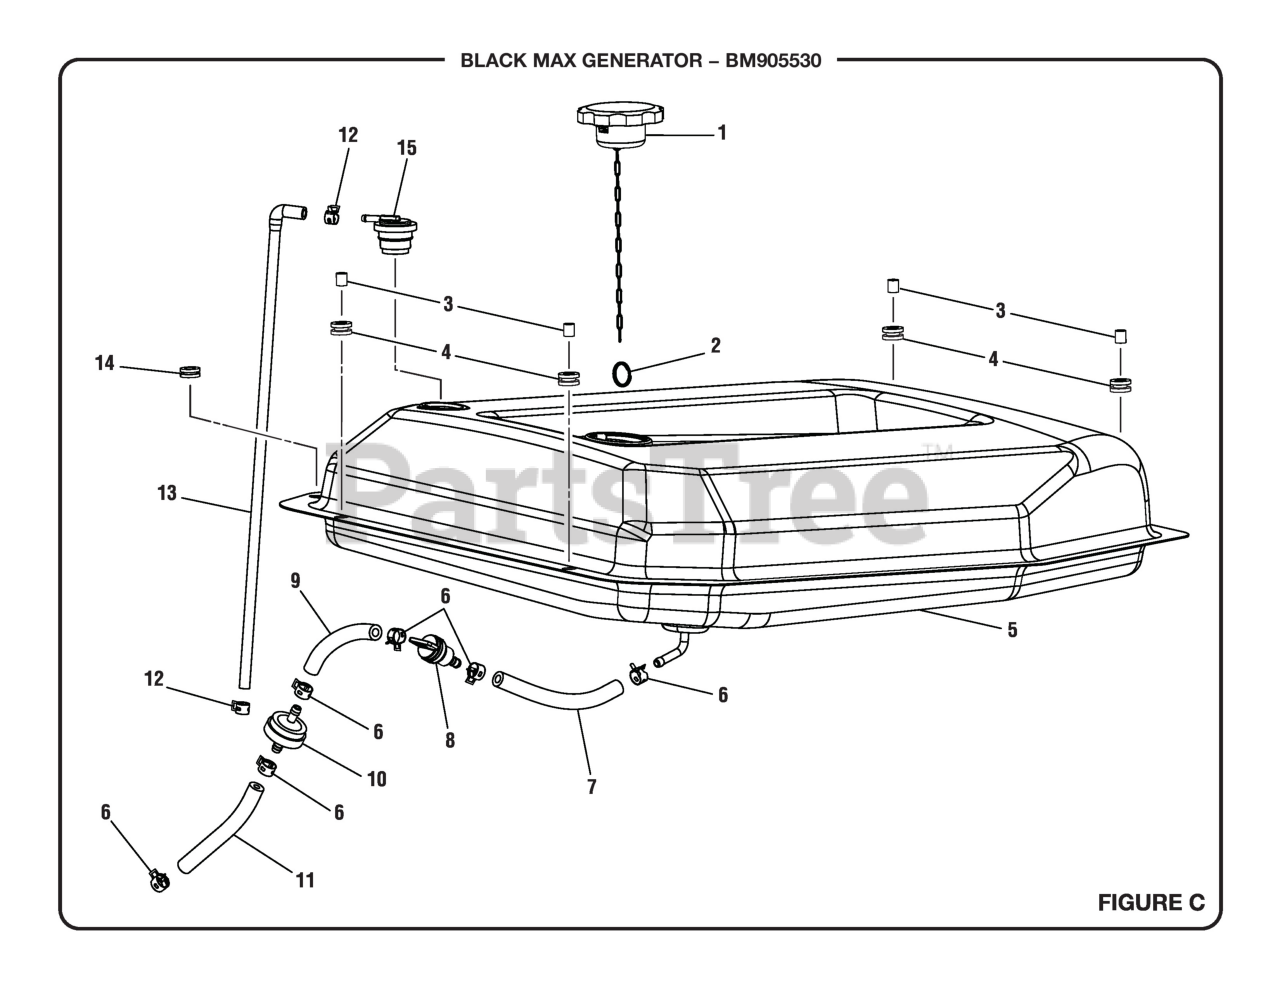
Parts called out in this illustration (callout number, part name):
1	Fuel Cap Assembly
2	Ring Clip
3	Spacer (Fuel Tank Isolator)
4	Bushing (Fuel Tank Isolator)
5	Fuel Tank
6	Fuel Line Clamp (1/2 in.).
7	Fuel Line (6.4 mm x 72 mm)
8	Fuel Shut Off Valve
9	Fuel Line (115 mm)
10	Fuel Filter Inline (1/4 in.)
11	Fuel Line (173 mm)
12	Fuel Line Clamp (7/16 in., BM903611)
13	Vapor Hose (410 mm)
14	Fuel Hose Protector
15	Fuel Tank Vapor Vent
